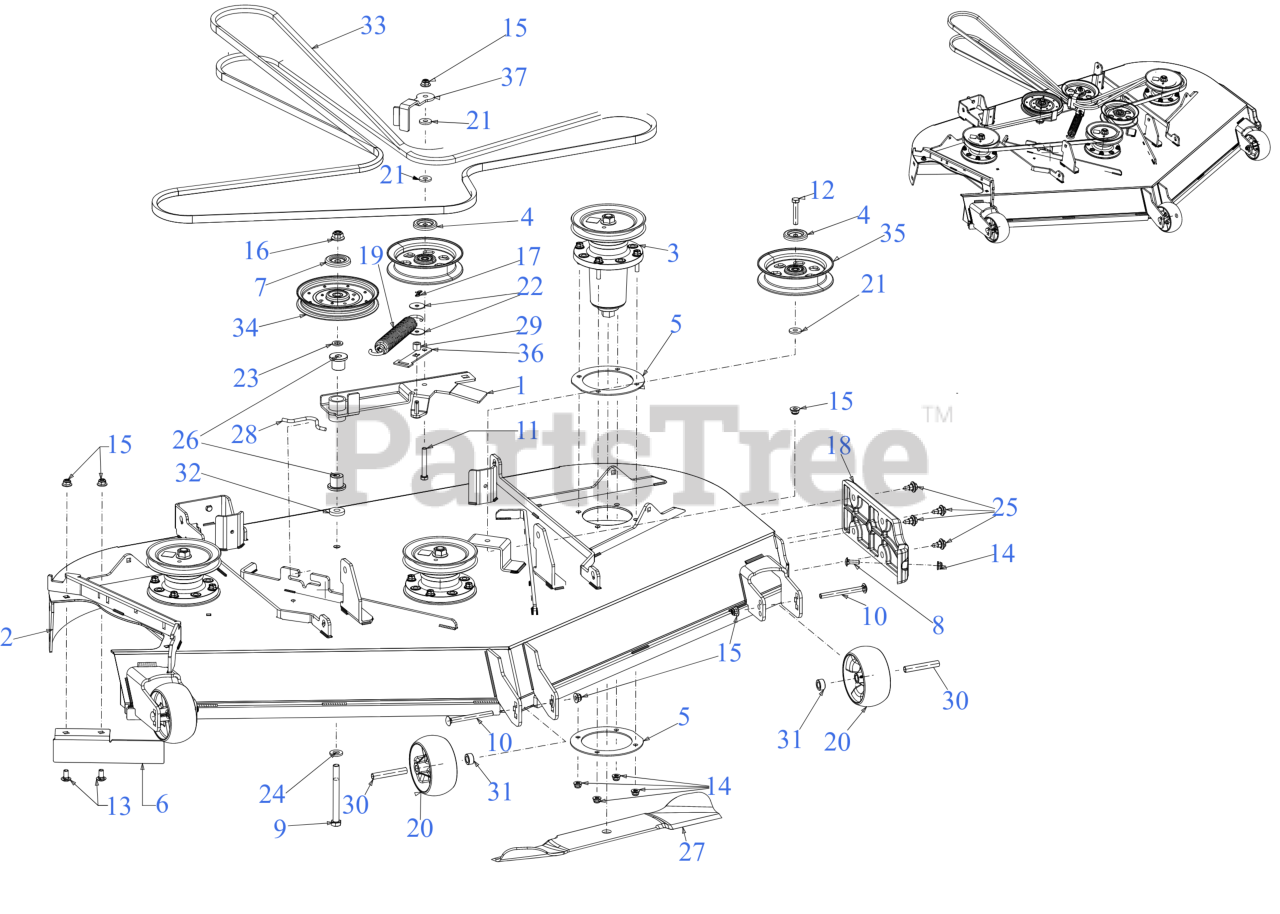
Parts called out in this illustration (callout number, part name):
1	54/60" DECK IDLER ASSEMBLY
2	60" FAB DECK SHELL
3	SPINDLE ASSEMBLY
3	Cub Cadet 60" SPINDLE ASSEMBLY (07386)
4	PULLEY CAP 1.875 DIA
5	SPINDLE PLATE
6	60" DECK CHUTE BAFFLE
7	PULLEY CAP (.540 x 2.041 DIA)
8	CARRIAGE BOLT 5/16-18 x 1.00
9	BOLT-HEX 1/2-13X5.0 GR5
10	CARRIAGE BOLT 3/8-16 x 4.00 GR5
11	HEX SCREW-3/8-16X2.5 GR5
12	SCREW 3/8-16 x 2.0 GR5
13	CARRIAGE BOLT 3/8-16 x .75
14	FLANGE LOCK NUT 5/16-18
17	BOW TIE COTTER PIN 1/4-5/16
18	DECK SKID PLATE
19	SPRING 1.25" DIA x 8.5" LONG
20	DECK WHEEL
20	WHEELS-DELUXE 5"
21	FLAT WASHER .385 x 1.00 x .135
22	FLAT WASHER .322 ID x 1.25 x .060
23	FLAT WASHER
24	FLAT WASHER .531X1.060X.134
25	SHOULDER SCREW .43X.29X5/16-18 TT
26	FLANGE BEARING
28	DECK SPRING HOOK
30	SPACER .38X.49X3.05LG
31	SPACER-.505 1D
32	SPACER PLATE
33	V-BELT B SEC x 162.25
33	Cub Cadet DECK BELT
34	IDLER PULLEY 6.0" DIA
35	5" FLAT IDLER PULLEY
36	BELT KEEPER
37	54/60" IDLER KEEPER
